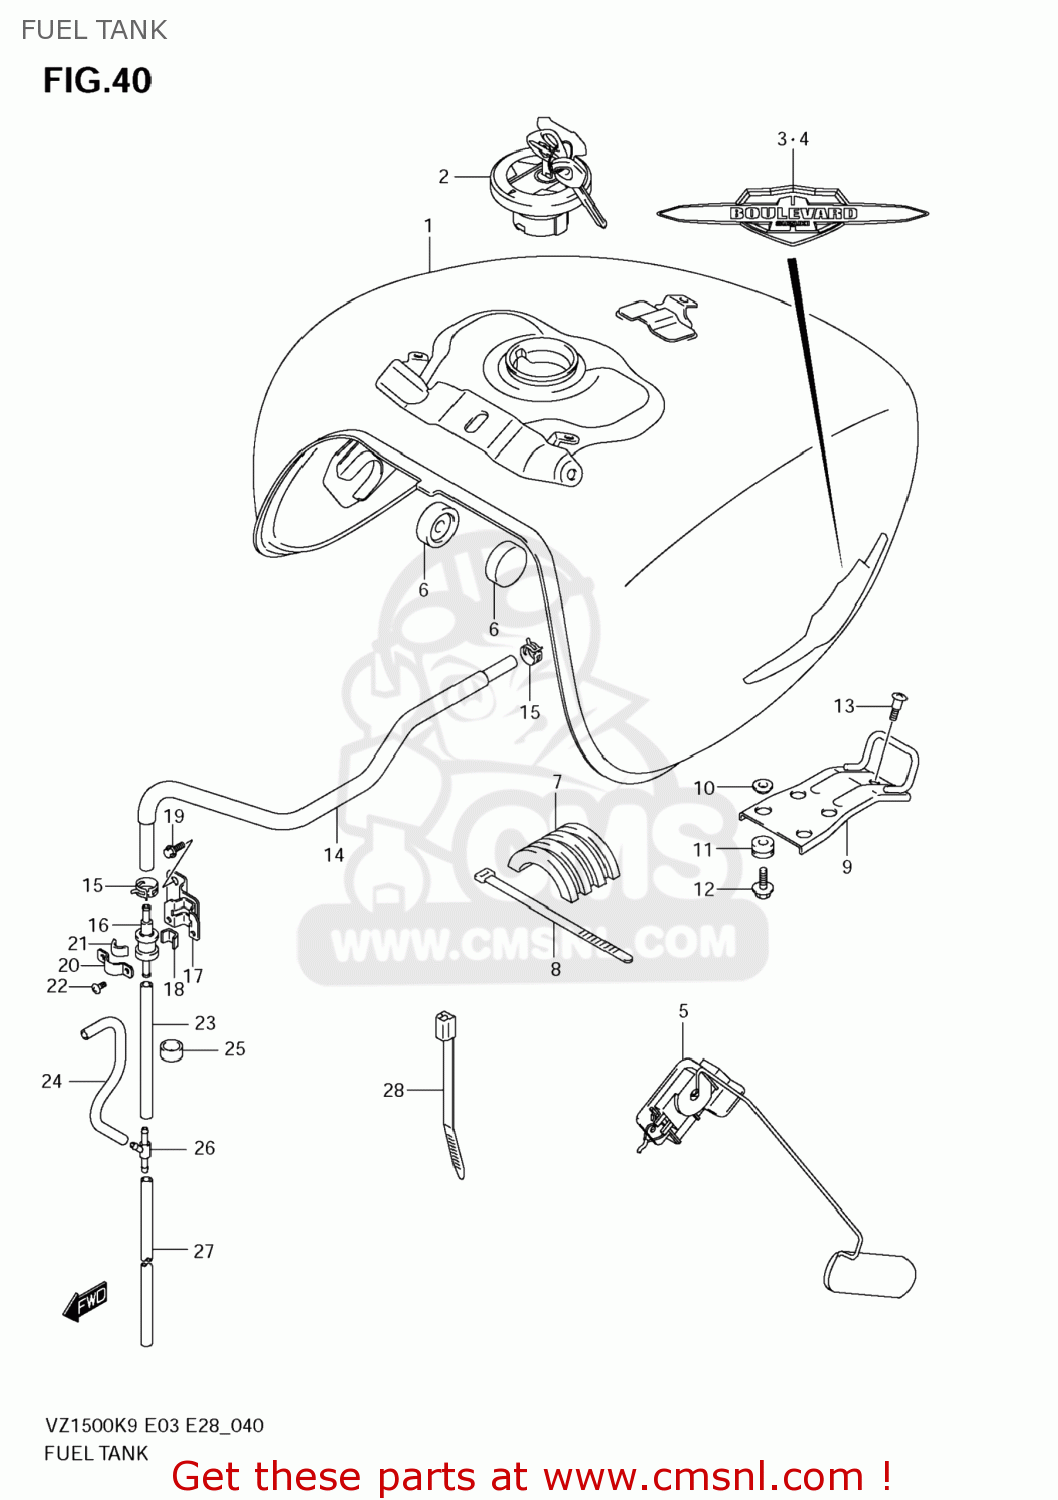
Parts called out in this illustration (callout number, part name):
1	TANK ASSY,FUEL(RED)
2	CAP SET,FUEL TANK
3	EMBLEM,FUEL TANK,R
4	EMBLEM,FUEL TANK,L
5	GAUGE ASSY,FUEL LEVEL SENDER
6	CUSHION
7	CUSHION,FUEL TANK LWR
8	CLAMP(L:300)
9	BRACKET,FUEL TANK RR
10	WASHER
11	CUSHION
12	BOLT(6X20)
13	BOLT
14	HOSE,TANK & BREATHER VALVE
15	CLIP
16	VALVE,FUEL TANK BREATHER
17	BRACKET,BREATHER VALVE
18	CUSHION
19	BOLT
20	PLATE,FUEL TANK BREATHER NO.2
21	CUSHION
22	SCREW
23	HOSE(5X9X600)
24	HOSE,TANK BREATHER NO.2
25	HOSE(13.5X16.5X600)
26	3 WAY
27	HOSE(5X8.2X600)
28	CLAMP(L:190)
